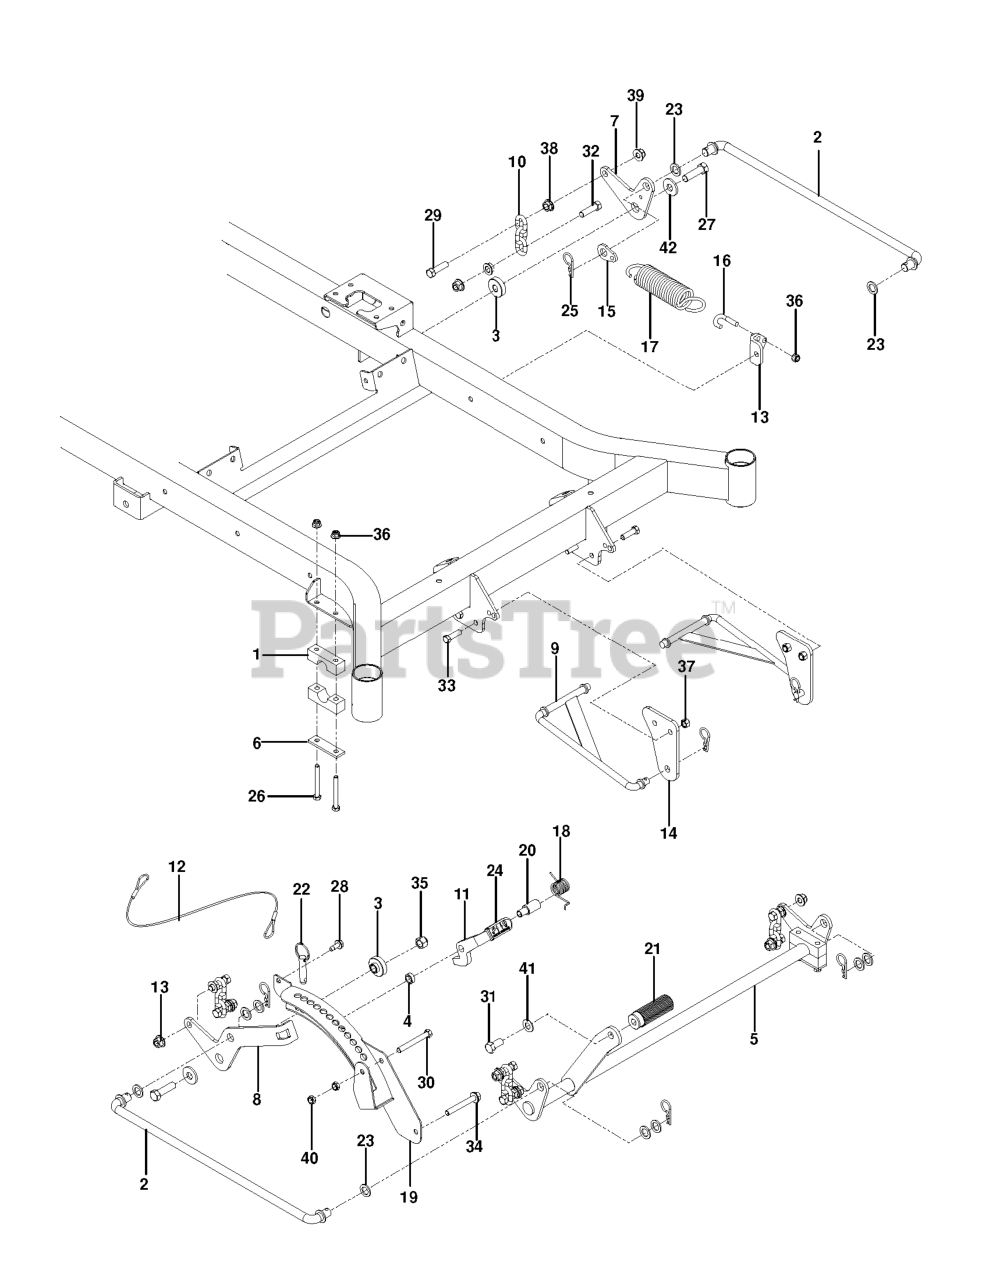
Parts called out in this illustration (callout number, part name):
1	PILLOW BLOCK
2	CROSS LINK
3	IDLER SPACER
4	SPACER, .3
5	SHAFT FRONT LIFT BLK
6	REINFORCEMENT BAR
7	BELLCRANK, RR, LIFT
8	BELLCRANK, RR, RT
9	STRUT LINKAGE
10	LIFT CHAIN - 3 LINK
11	LATCH, TRANSPORT
13	MOUNT, SPRING
14	MOUNT, STRUT
15	TAB, SPRING
16	J-BOLT
18	SPRING, TORSION
19	HEIGHT, ADJUST, DECK
20	PIVOT, LATCH, TRANSPORT
21	PEDAL, DECK HEIGHT
22	PIN, 1/2 X 1 1/2, DETENT RING
23	BUSHING
24	GRIP, TRANSPORT-RELEASE
25	PIN, COTTER 1 3/4
26	HCS 5/16C X 2-3/4
27	HCS 1/2-13 X 1 3/4 GR 8
28	BOLT 5/16-18 X 3/4
29	HCS 7/16C X 1 1/2
30	HCS 3/8C X 3
31	HHCS 1/2-13 X 1
32	HCS 7/16 - 14 X 1 3/4
33	HCS 3/8C X 1 1/4 GR5
34	HHFS 3/8-16 X 2 3/4
35	NUT 1/2-13 HEX NYLOC ZD
36	5/16-18 NYLOC FLANGE NUT
37	NUT 3/8-16 NYLOC
38	NUT 7/16C WHIZ
39	NUT 7/16-14 HEX WHIZ LK
40	NUT HEX 3/8-16 NYLON, THIN
41	WASHER, 7/16 DISC SPRING
42	WASH USS FLAT 1/2
